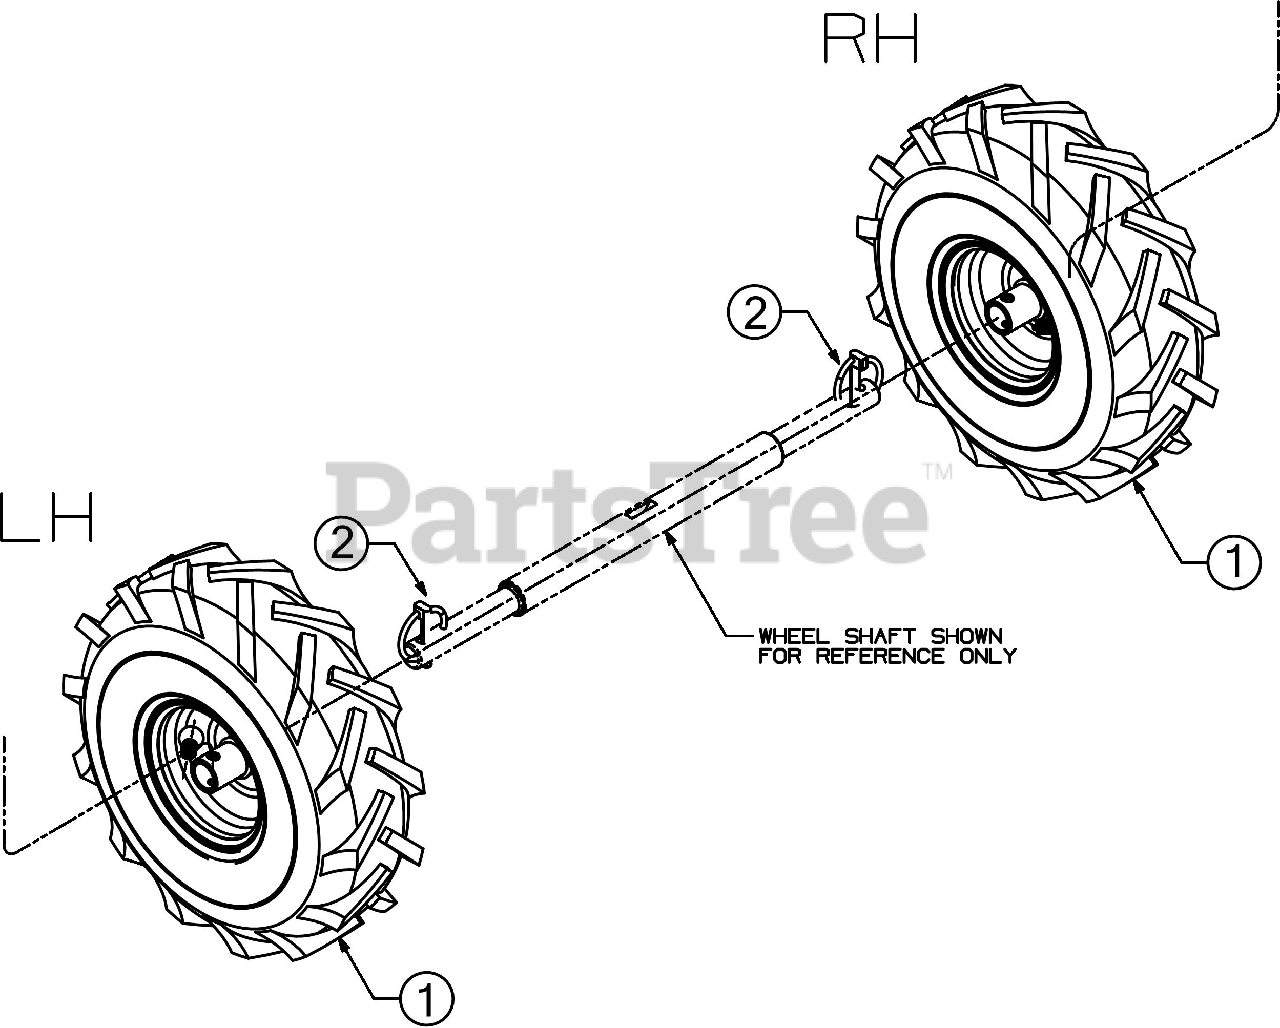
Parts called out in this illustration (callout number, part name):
1	WHEEL ASSEMBLY (11 x 4-4)
1	TUBELESS VALVE
1	TIRE-TILLER AG 11 x 4-4
